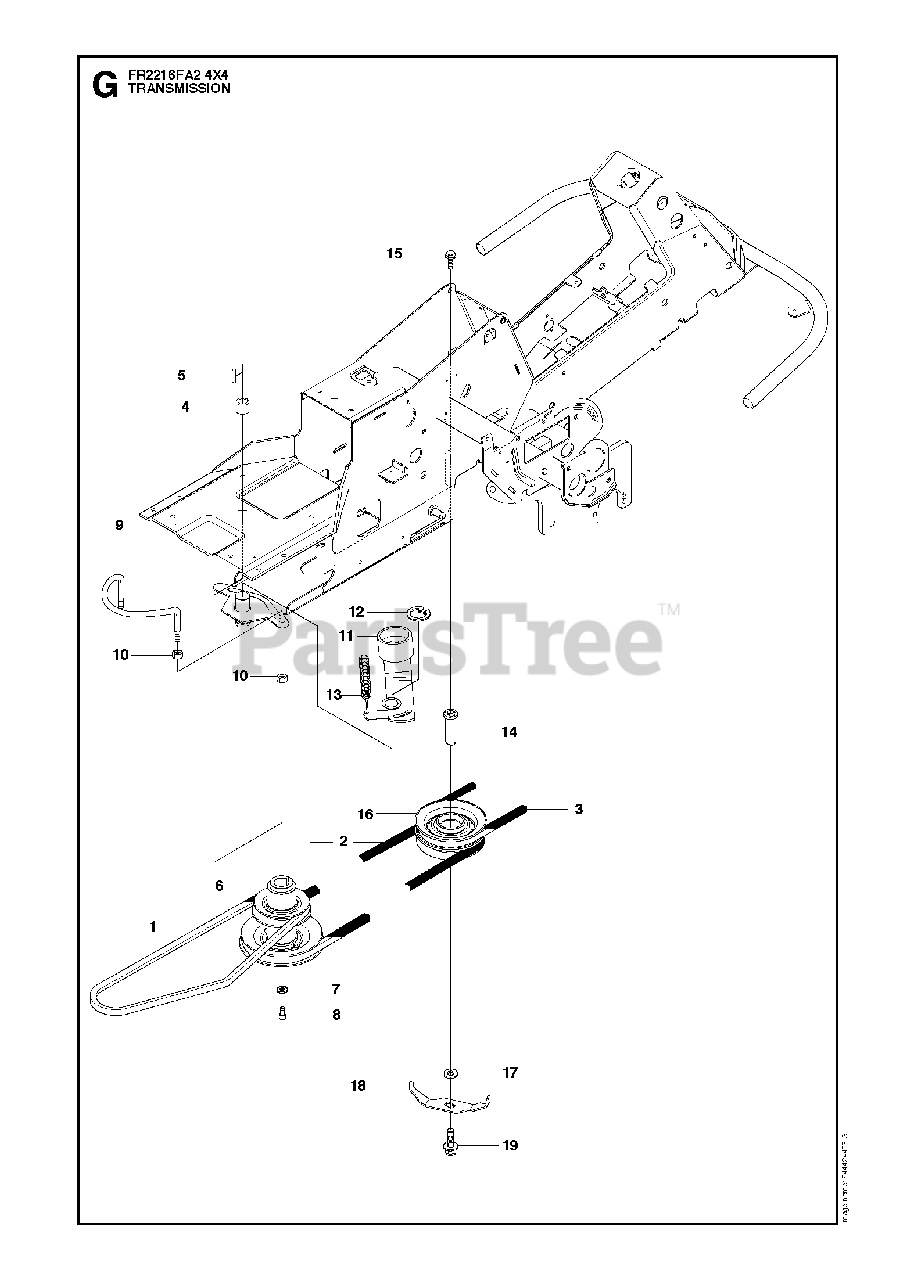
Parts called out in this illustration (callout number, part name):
1	BELT
2	BELT
3	BELT
9	BELT GUIDE
11	TENSIONER
12	RETAINING RING SGA 25
14	SHAFT
18	BELT GUIDE
19	BOLT
